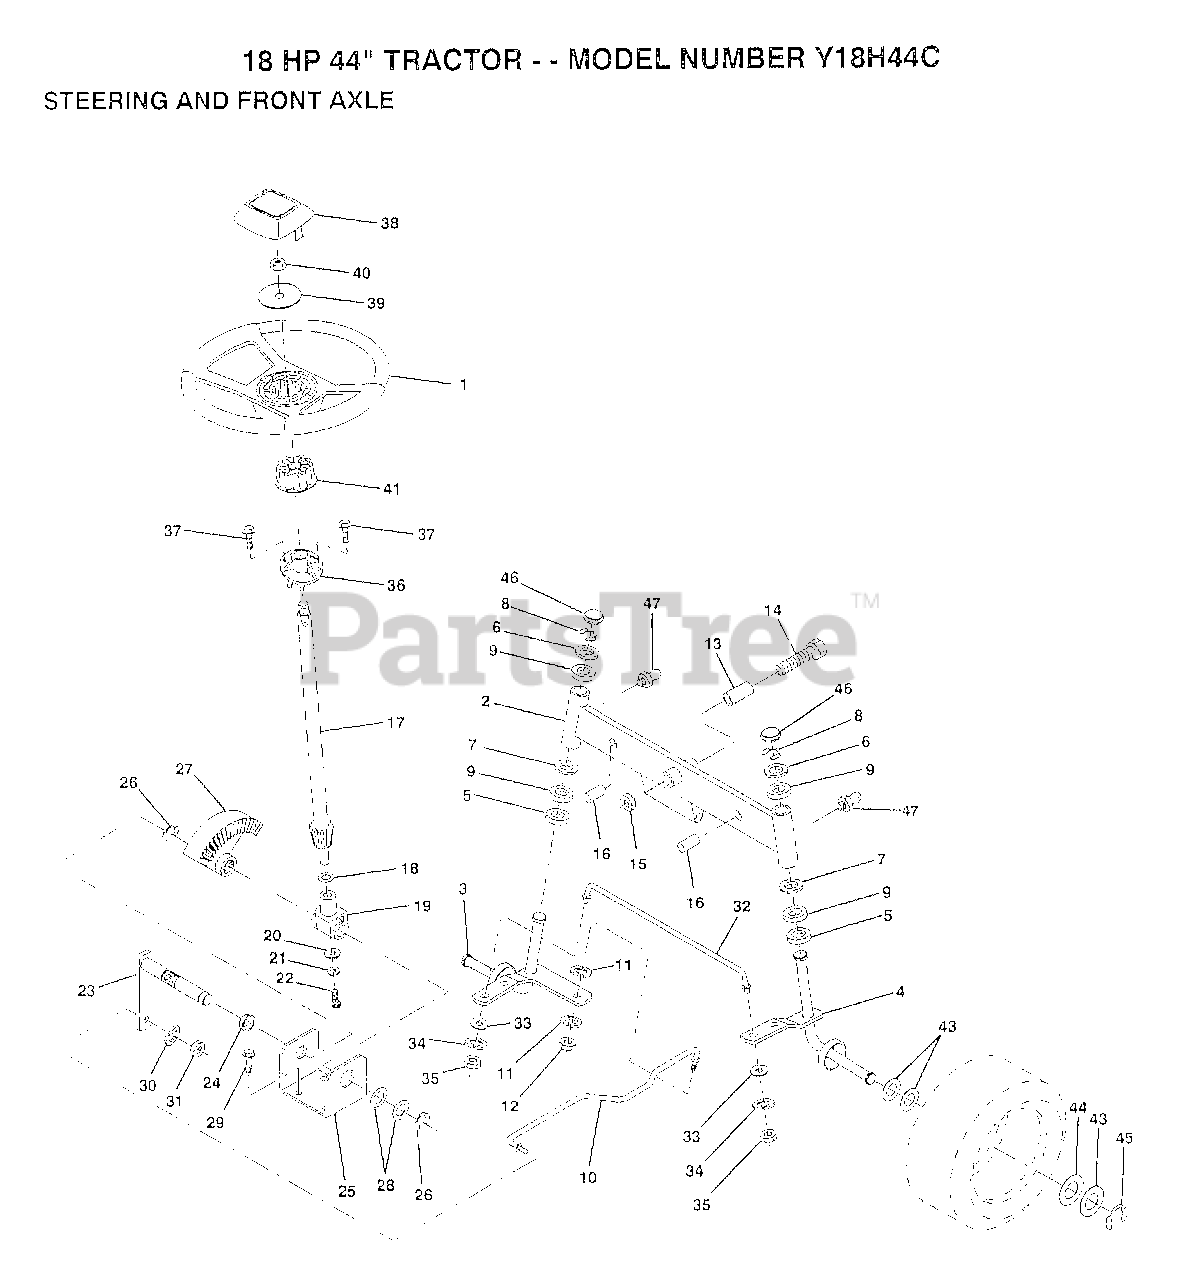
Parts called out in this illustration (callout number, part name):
2	FRONT AXLE
3	SPINDLE LH
4	SPINDLE RH
5	WASHER .T
6	WASHER
7	WASHER
8	RING
9	COL. SRTG. BEAR.
11	LOCKWASHER
13	BEARING
14	BOLT HEX 5/8-11
15	"NUT-LOC,FLANGE LT"
16	AXLE PIN
18	THRUST WASHER
19	SUPPORT.SHAFT
21	LOCKWASHER
22	"SCREW,SPECIAL"
24	NYLINER T
25	"BRKT,STEERING"
26	RING
27	GEAR SECTOR
28	WASHER .T
29	SCREW
30	LOCKWASHER
32	TIE ROD
33	WASHER M
34	LOCKWASHER
35	NUT.LOCK.5/16-24
38	INSERT STEERING
39	WASHER
41	ADAPTER LT
43	WASHER
44	WASHER
45	RING
46	CAP
47	ZERK M
